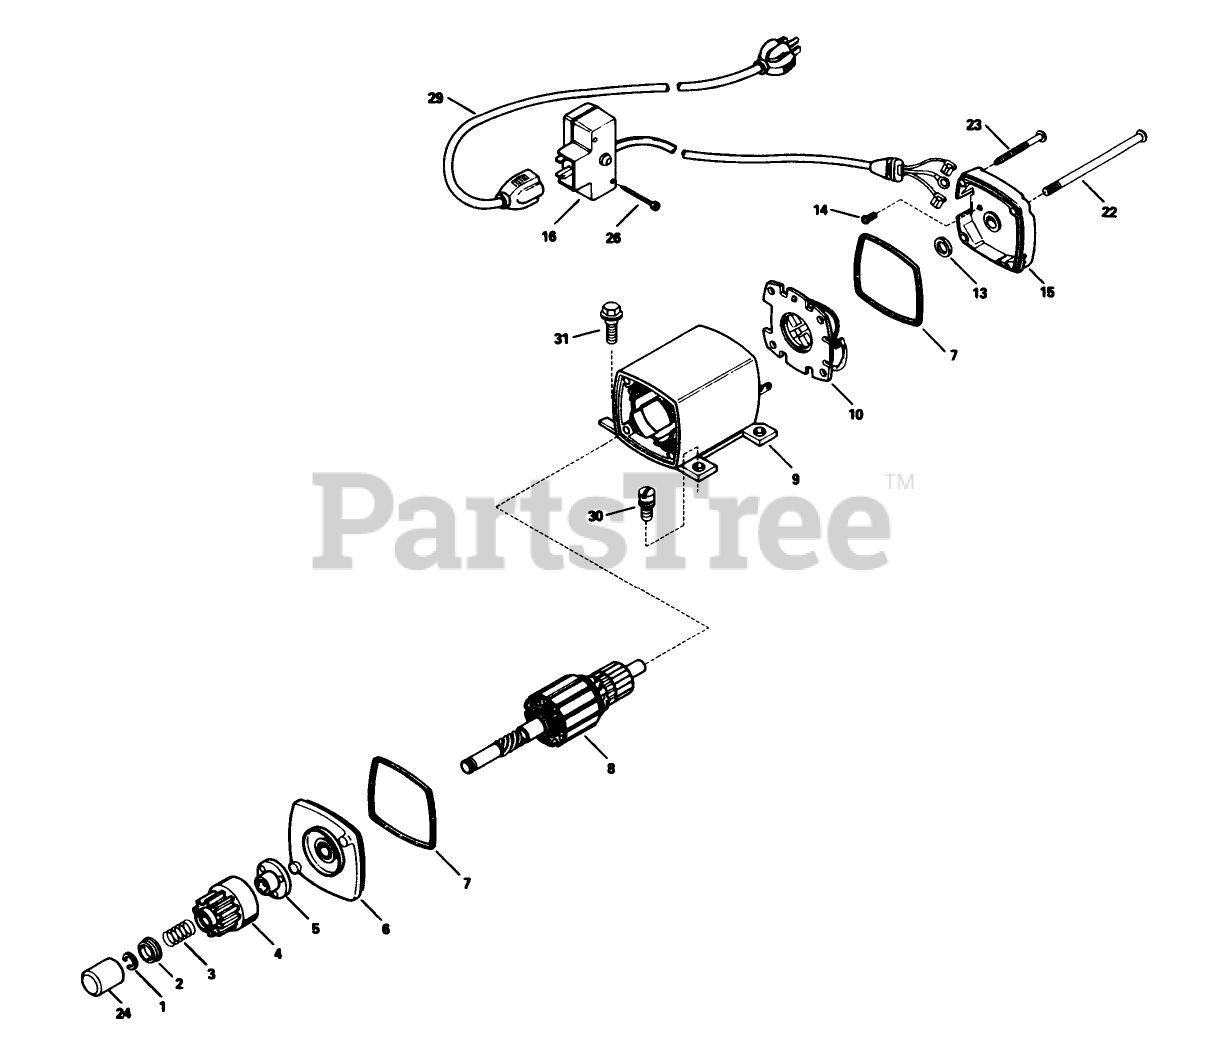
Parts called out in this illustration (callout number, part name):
1	Ring-Retainer
2	Retainer-Spring
3	Spring-Anti Drift
4	Gear
5	Nut-Engaging
6	Cap Assembly-Cap End (Incl. Ref. #7)
7	O-Ring
8	Armature
9	Housing Assy.
10	Card ASM
13	Washer-Thrust
14	Screw-Ground
15	Cap Assembly (Incl. Ref. #7)
16	Box Assembly-Switch (Incl. Ref. #26)
22	Bolt-Case
23	Screw-Ground
24	Cover-Dust
26	Screw
29	Cord-Extension
30	Screw
31	Screw (1/4-20x1/2)
